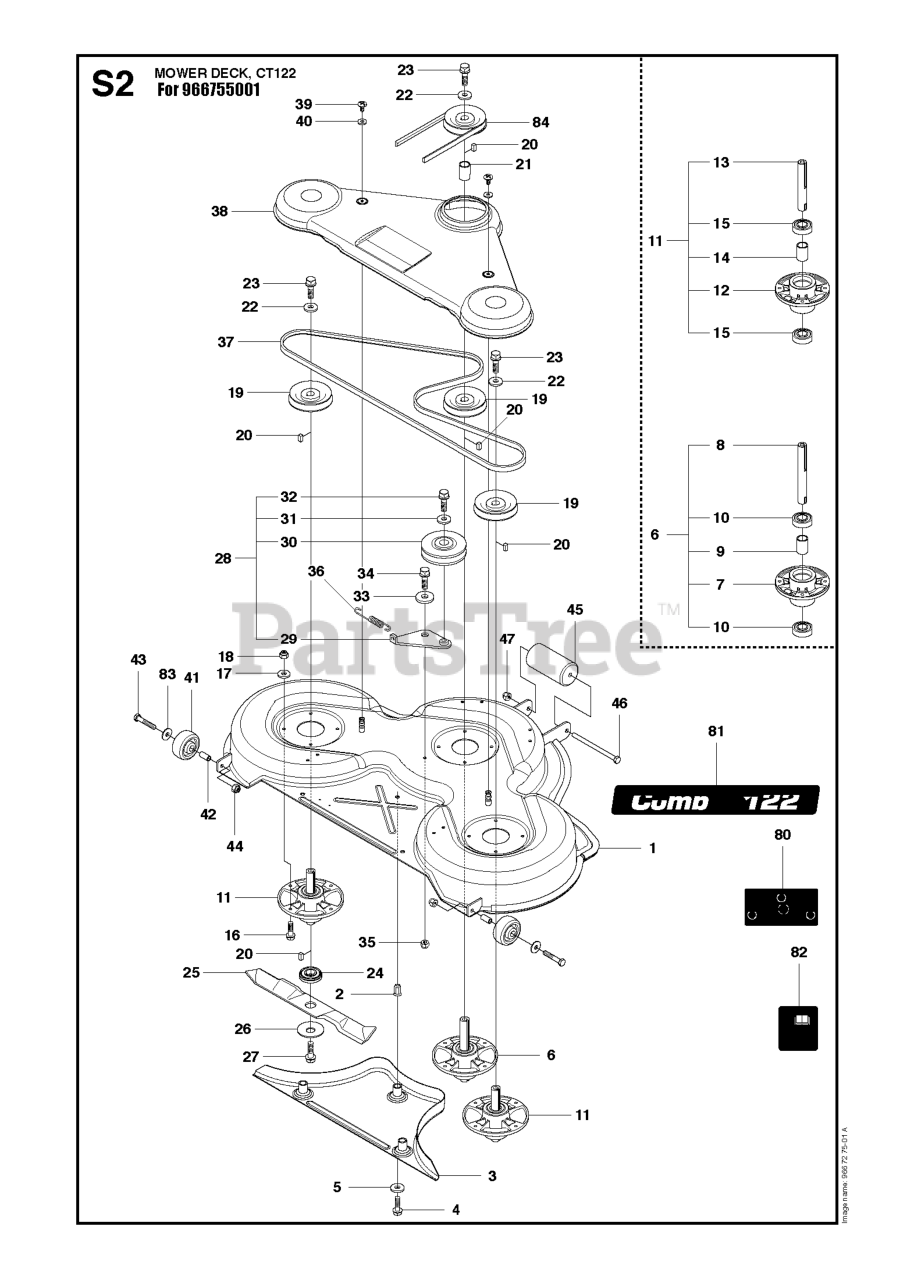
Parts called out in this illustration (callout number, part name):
4	SCREW
5	WASHER BRB 8.4X17
7	BEARING HOUSING
10	BALL BEARING
12	BEARING HOUSING
15	BALL BEARING
17	WASHER BRB 8.4X17
18	LOCKNUT M8
28	BELT TENSIONER ASSY
29	BELT TENSIONING ARM
33	WASHER
35	LOCKNUT M8
41	WHEEL
45	ROLLER
